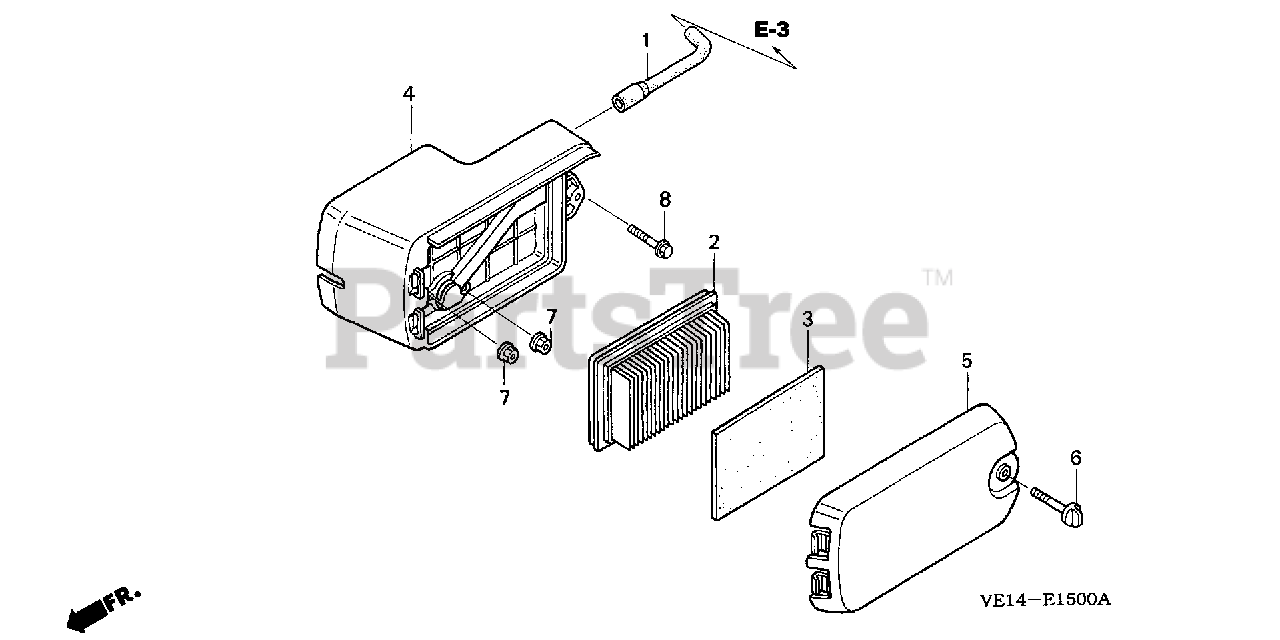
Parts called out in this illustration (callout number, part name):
1	TUBE, BREATHER (110MM)
2	ELEMENT, AIR CLEANER
3	FILTER (OUTER)
4	HOUSING, AIR CLEANER
5	COVER, AIR CLEANER
6	BOLT, AIR CLEANER (6MM)
7	NUT, FLANGE (6MM)
8	BOLT, FLANGE (6X32)
